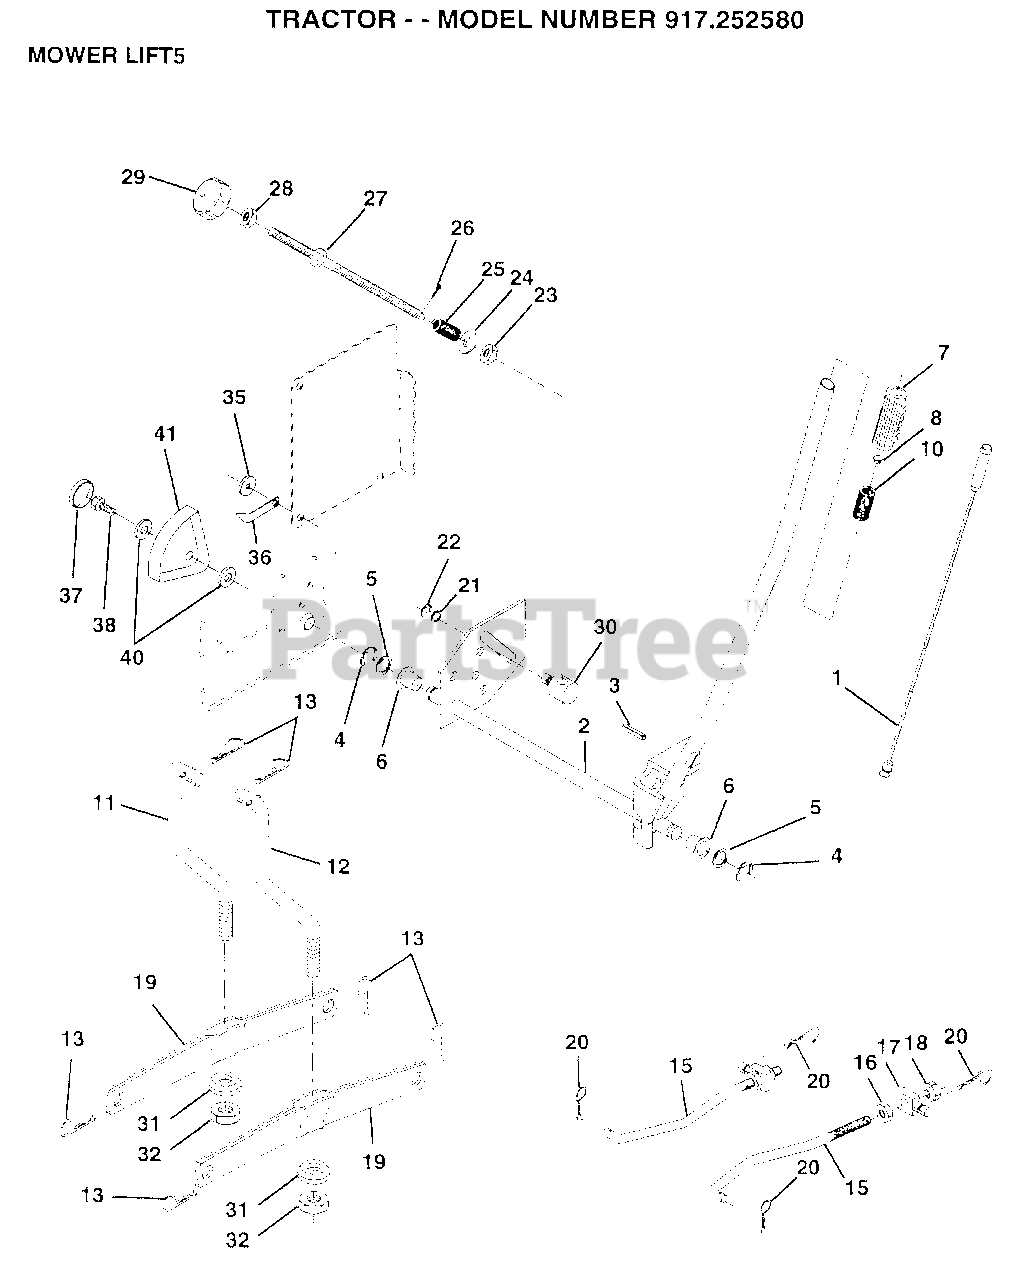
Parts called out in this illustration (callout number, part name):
1	WIRE ASM
2	SHAFT.LIFT.ASM.RH
3	PIN GROOVE
5	WASHER
6	NYLON BEARING
7	GRIP HANDLE
15	LINK.FRONT
16	NUT
17	TRUNION
18	NUT.LK.W/WSH.1/2.
19	ARM SUSP REAR
20	RETAINER.SPRING
21	WASHER
22	KLIP RING
23	NUT T
24	WASHER
25	SPRING T
28	NUT
29	KNOB INF 3/8-16
30	TRUNION LT
31	BEARING PVT LH
32	NUT.CROWNLOCK.3/8
35	WASHER T
36	POINTER HGT IND
37	"PLUG,HOLE"
38	SCREW
40	WASHER
41	HEIGHT INDICATOR
